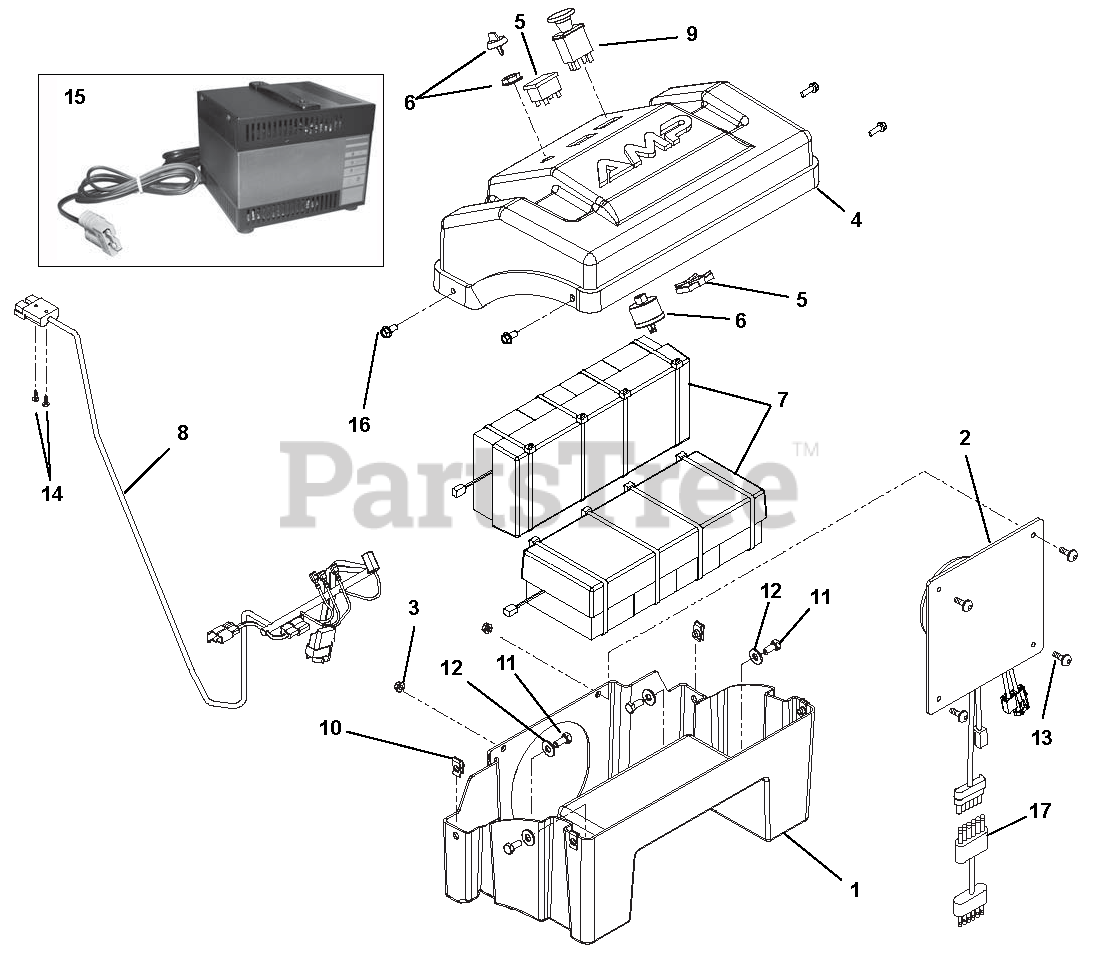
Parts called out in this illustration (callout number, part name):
1	BOX, BOTTOM BATTERY
2	ASSY, DRIVE CONTROLLER
3	@NUT-LK-TOP-FLG .25-20 YWZC
4	COVER, BATTERY BOX-DESIGN 2
5	METER, BATTERY DISCHARGE 48V
6	SWITCH-IGNITION 2-POS W/KEY
7	TRAY, AMP-W/BATTERY
8	HARNESS, MAIN ESNOW W/FUSE
9	SWITCH, CLUTCH
10	NUT-RTNR .25-20X.56
11	@BLT-HEX .31-18X.75 GR5 YWZC
12	@WSHR-FL-STL.38X.875X.083 YWZC
13	SCR-MCH .25-20X.63 BTNHDSKT YZ
14	SCR-TAP #8X.50 PLASTITE SLHXHD
15	CHARGER,BAT.48V5A-TEMP/HIB58.8
16	BLT-HEX .25-20X.75 HWH YZ GR5
17	HARNESS, MTR/CNTL JUMPER-CE
